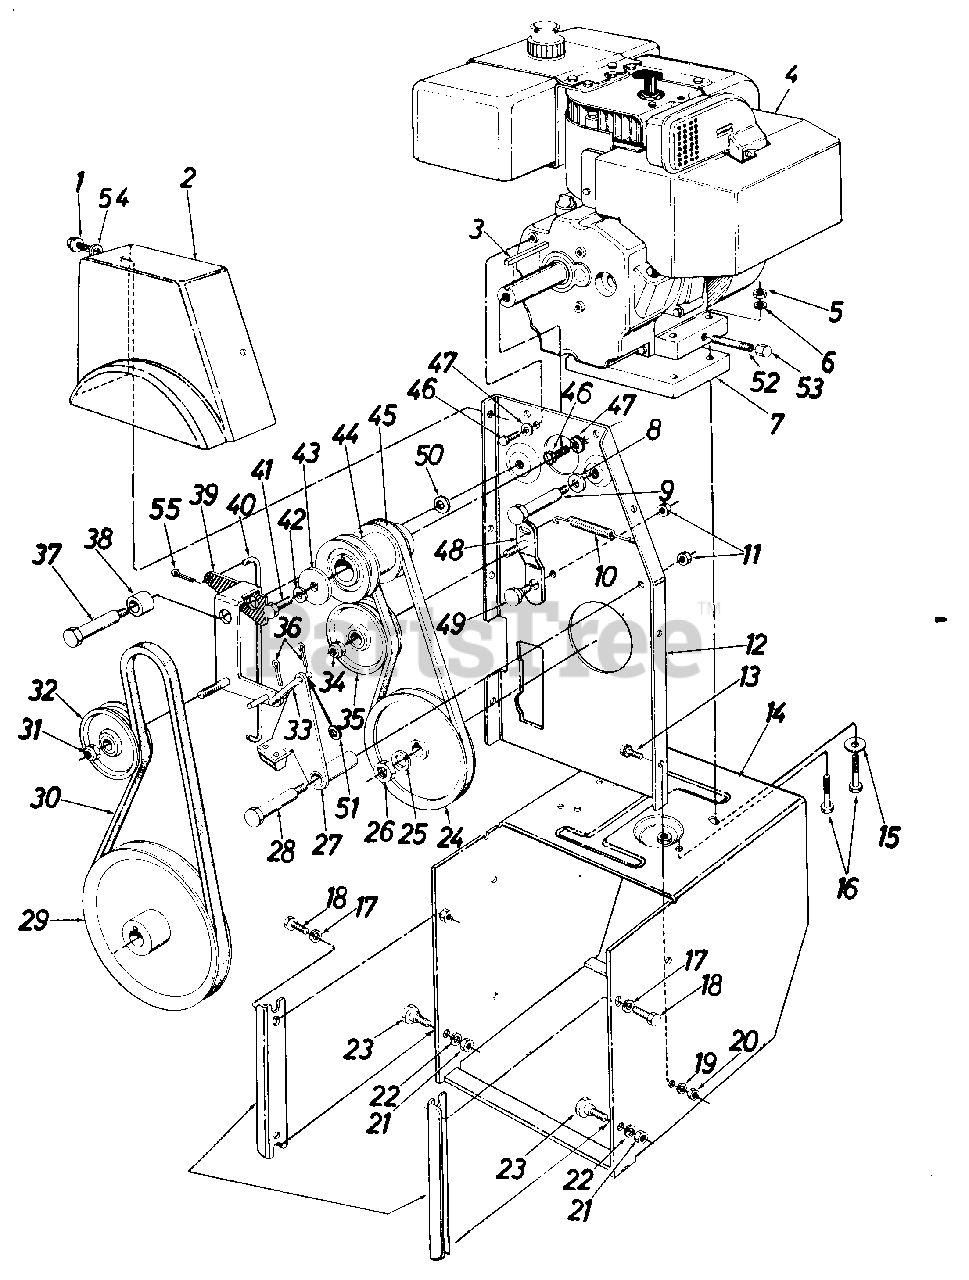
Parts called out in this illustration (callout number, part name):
1	Hex AB-Tap Scr. 5/16 x .75" Lg.
2	Belt Cover
3	Sq. Key 1/4" X 1.50" Lg.
4	Engine
5	Hex Nut 5/16-18 Thd.
6	L-Wash. 5/16" I.D.
7	Engine Spacer Ass'y.
8	Bell-Wash. .40 I.D. x .88 O.D.
9	Shld. Bolt .498" Dia. x 3.00" Lg.
10	Ext Spring .38 O.D. x 3.18" Lg.
11	Hex Cent. L-Nut 3/8-16 Thd.
12	Engine Brkt. Ass'y.
13	Hex Sems Scr. 5/16-18 x .75" Lg.
14	Frame Ass'y.
15	Fl-Wash. .345 I.D. x .75 O.D. x .060
16	Hex Bolt 5/16-18 x 2.50" Lg.
17	L-Wash. 3/8" I.D. H.D.
18	Pilot Scr. 3/8-16 x .88" Lg.
19	L-Wash. 5/16" I.D.
20	Hex Nut 5/16-18 Thd.
21	Hex Nut 3/8-16 Thd.
22	L-Wash. 3/8" I.D. H.D.
23	Shld. Bolt .498" Dia. x .340" Lg.
24	V-Puiley .628 I.D. x 7.50 O.D.
25	L-Wash. for 5/8" I.D.
26	Hex Ins. Jam L-Nut 5/8-18 Thd.
27	Brake Brkt. Ass'y.
28	Shld. Bolt .498" Dia. x 2.00" Lg.
29	V-Pulley .875 I.D. x 10.12 O.D.
30	"V"-Belt
31	Hex Ins. Jam L-Nut 3/8-24 Thd.
32	Fl-Idler w/Flanges 3.0 O.D.
33	Brake Linkage Ass'y.
34	Hex Ins. Jam L-Nut 3/8-24 Thd.
35	3.0" O.D. Fl-Idler w/Flanges
36	Int. Cot. Pin 3/32" Dia.
37	Shld. Bolt .625" Dia. x 2.750" Lg.
38	Spacer .75 O.D. x 1.00" Lg.
41	Hex Bolt 3/8-24 x 1.25" Lg.
42	L-Wash. 3/8" I.D. H.D.
43	Fl-Wash.
44	Engine Pulley Double Groove
45	"V"-Belt
46	Hex Bolt 5/16-24 x .62" Lg.
47	Bell-Wash. .345 I.D. x .88 O.D. x .060
48	Drive Idler Brkt. Ass'y.
49	Shld. Bolt .625" Dia. x .170" Lg.
50	Bell-Wash. .40 I.D. x 1.12 O.D.
51	Fl-Wash. .385" I.D. x .620" O.D.
52	Pipe Nipple - 1/4" Pipe Thd. x 3.5" Lg.
53	Hex Hd. Cap 1/4-18 Pipe Thd.
54	Fl-Wash. .340 I.D. x .62 O.D. x .62
55	Int. Cot. Pin 5/16" Dia.
